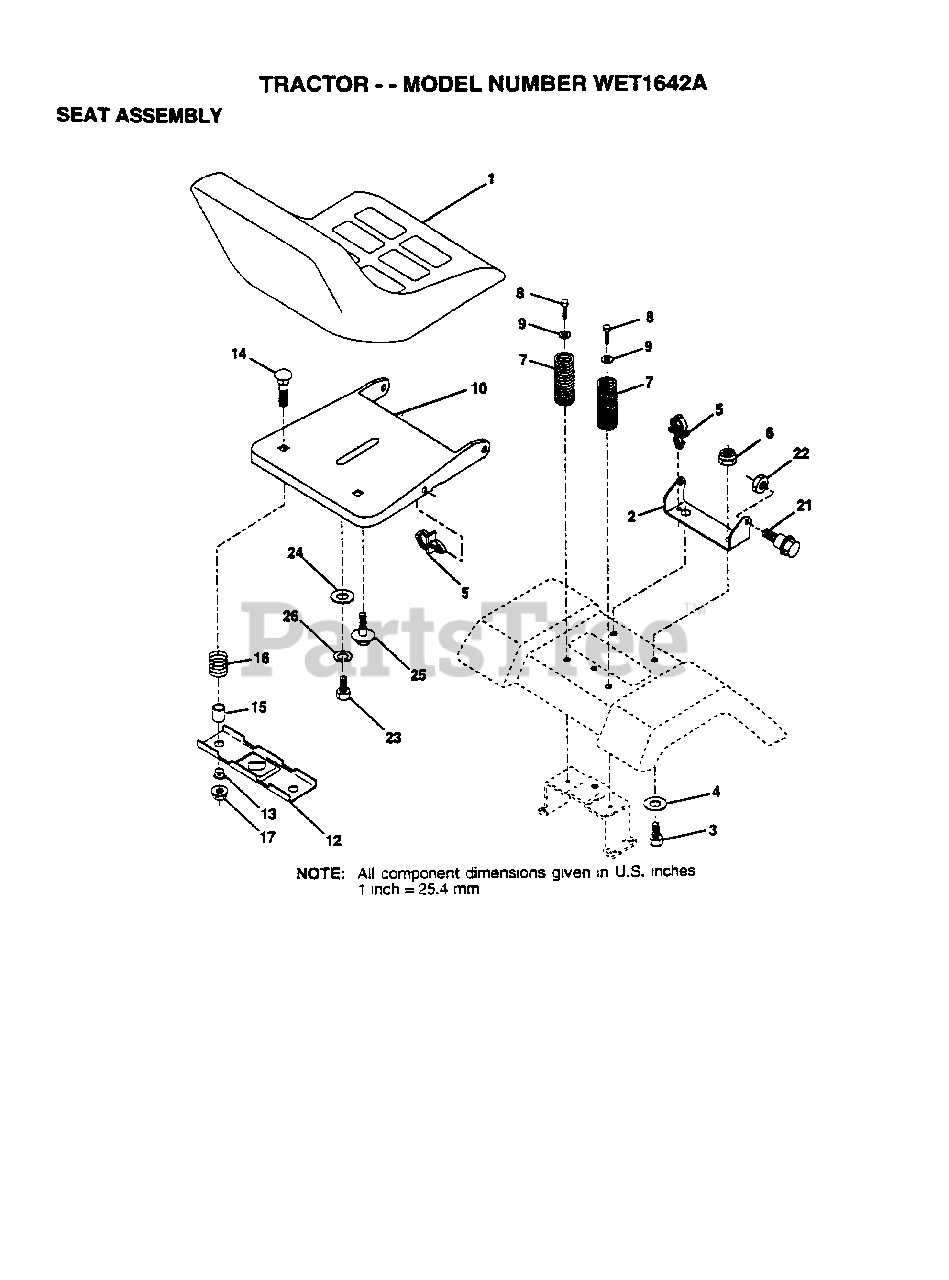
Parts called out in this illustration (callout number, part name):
2	BRACKET PVT SEAT
3	BOLT
4	WASHER PM
5	CLIP.PUSH-IN.HING
6	NUT
7	SPRING COMPRESSIO
8	SCREW GTV
9	WASHER
12	BRKT SWITCH
13	BUSHING
15	SPACER SPLIT
16	SPRING COMPRESSED
21	BOLT.SHLD.5/16-18
23	BOLT
24	WASHER
25	"BOLT,SHOULDER"
26	LOCKWASHER
